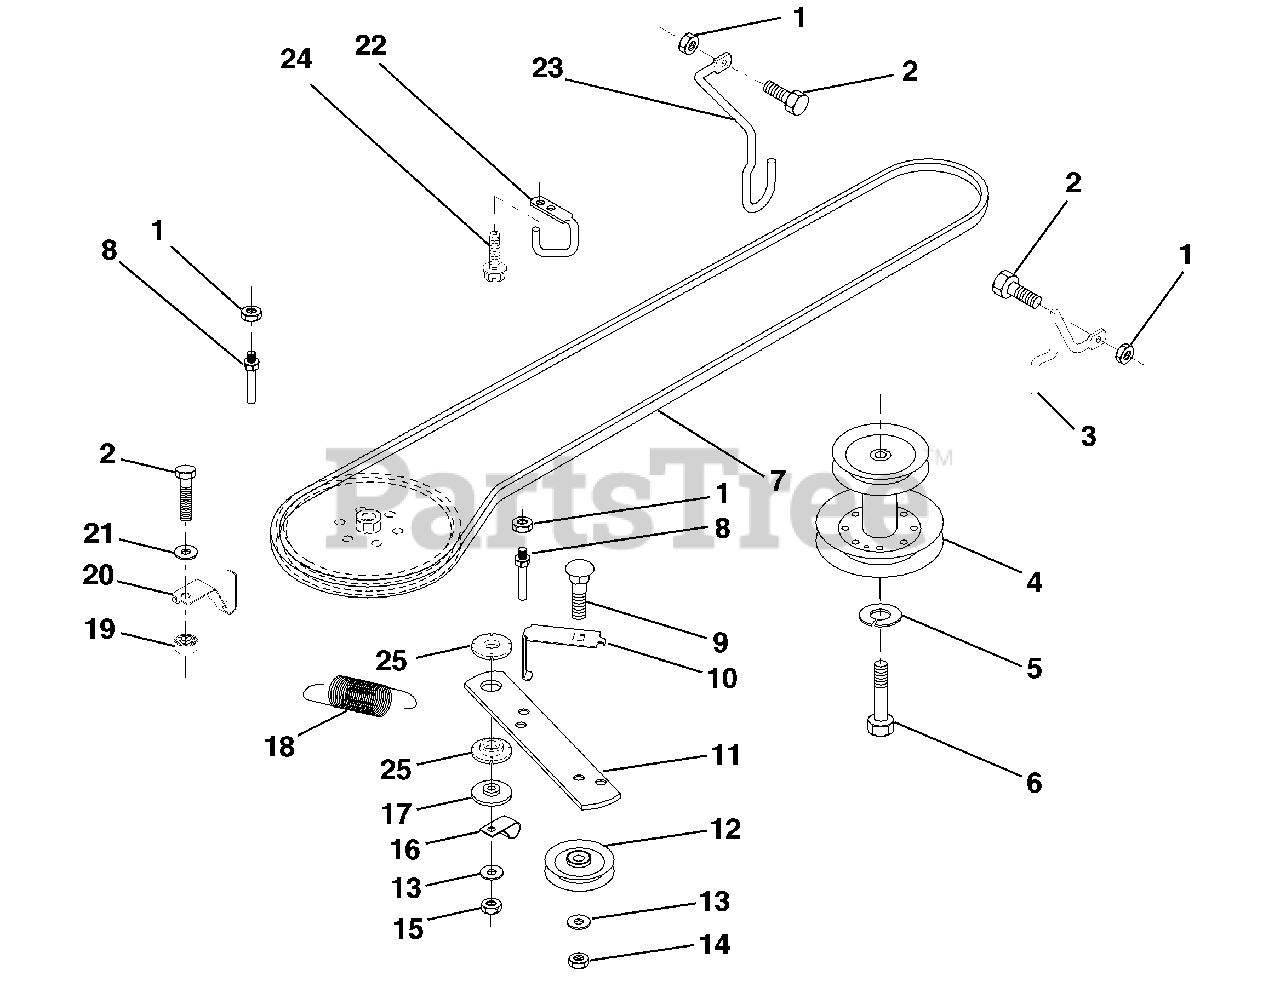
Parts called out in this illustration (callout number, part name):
1	Nut, Crownlock 5/16-18
2	Bolt, Hex Hd 5/16-18 UNC x 3/4
3	Keeper,Mower Drive, R. H.
4	Pulley, Engine
5	Washer, Lock 7/16
6	Bolt Hex 7/16-20 Gr. 5
7	Traction, V-Belt Drive
8	Keeper, T/A Ground Drive Belt
9	Bolt, Carr. 3/8-16 UNC x 1-1/2
10	Keeper, Belt Ground Drive Idler
11	Arm, Ground Drive Clutch
12	Idler, Flat
13	Washer 13/32 x 13/16 x 16 Ga.
14	Nut, Centerlock 3/8-16 UNC
15	Nut, Crownlock 3/8-16 UNC
16	Clip, Insulated
17	Spacer, Retainer
18	Spring Extension
19	Nut, Keps 5/16-18 UNC
20	Keeper, T/A Ground Drive Belt
21	Washer 11/32 x 5/8 x 16 Ga.
22	Keeper, Frame Ground Drive Belt
23	Keeper, Mower Drive, L. H.
24	Screw, Thd. Cut 1/4-20 x 1/2
25	Bushing Nylon Collered
